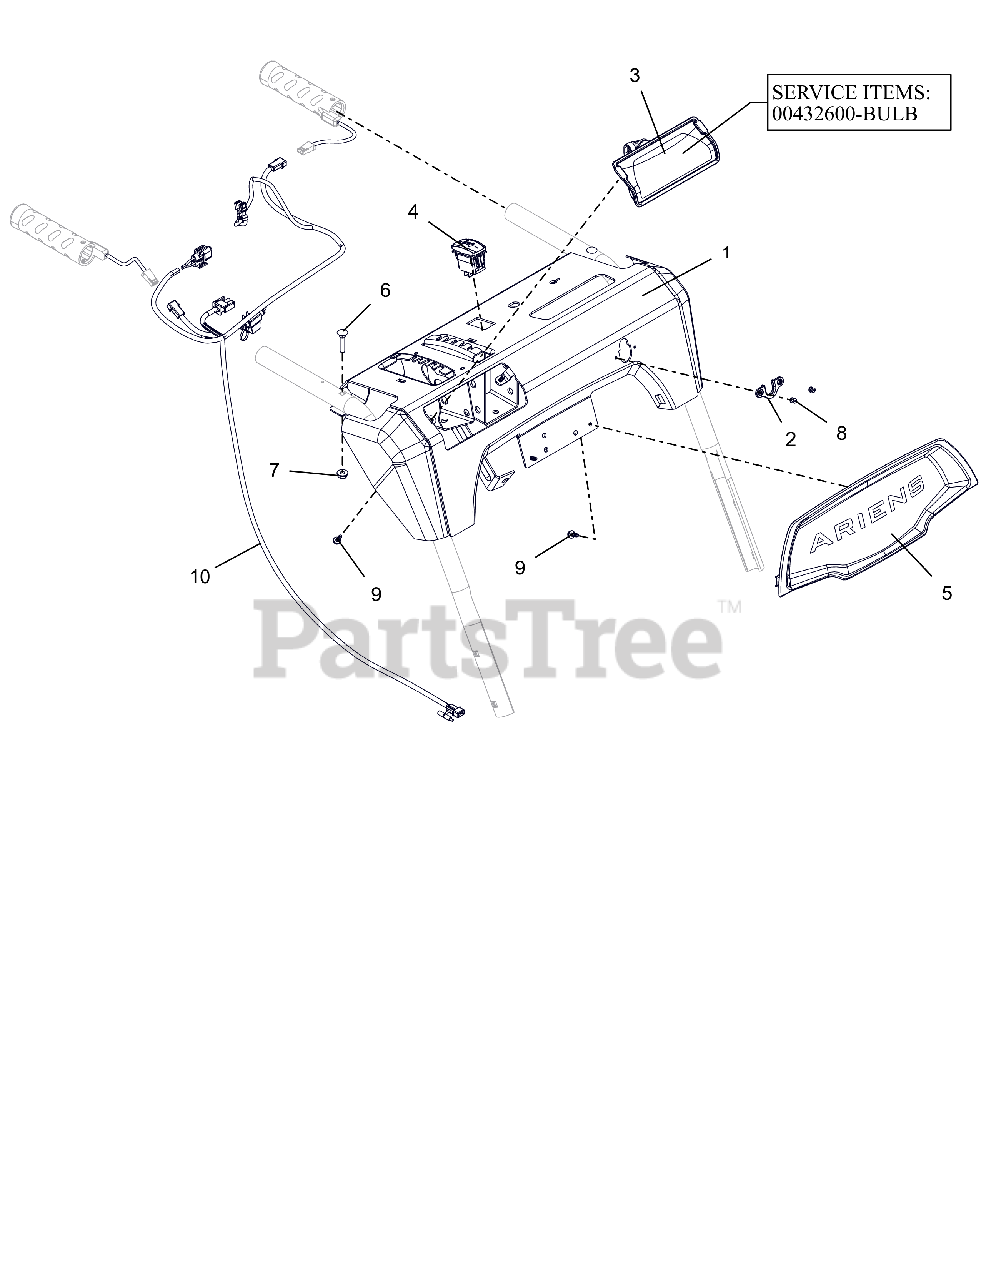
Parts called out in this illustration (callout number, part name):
1	PANEL, CONTROL-EFI QT W/DECAL
2	GROMMET, CABLE, QUICK TURN 2
3	HEADLIGHT ASY, HALO 20W 2SHOT
3	BULB, LIGHT-HALOGEN 20W
4	SWITCH,ROCKER SPST-ON/OFF
5	BEZEL, DASH - ARIENS LG DASH
6	BLT-RDHDXLSQNK.25-20X1.25 G5ZC
7	NUT-LK-CTR-FLG .25-20 ZC120
8	RVT-POP #43 .125X.313 STL ZINC
9	SCR, PLASTIC #10X.50
10	HARNESS,LIGHT&WARMER - EFI
